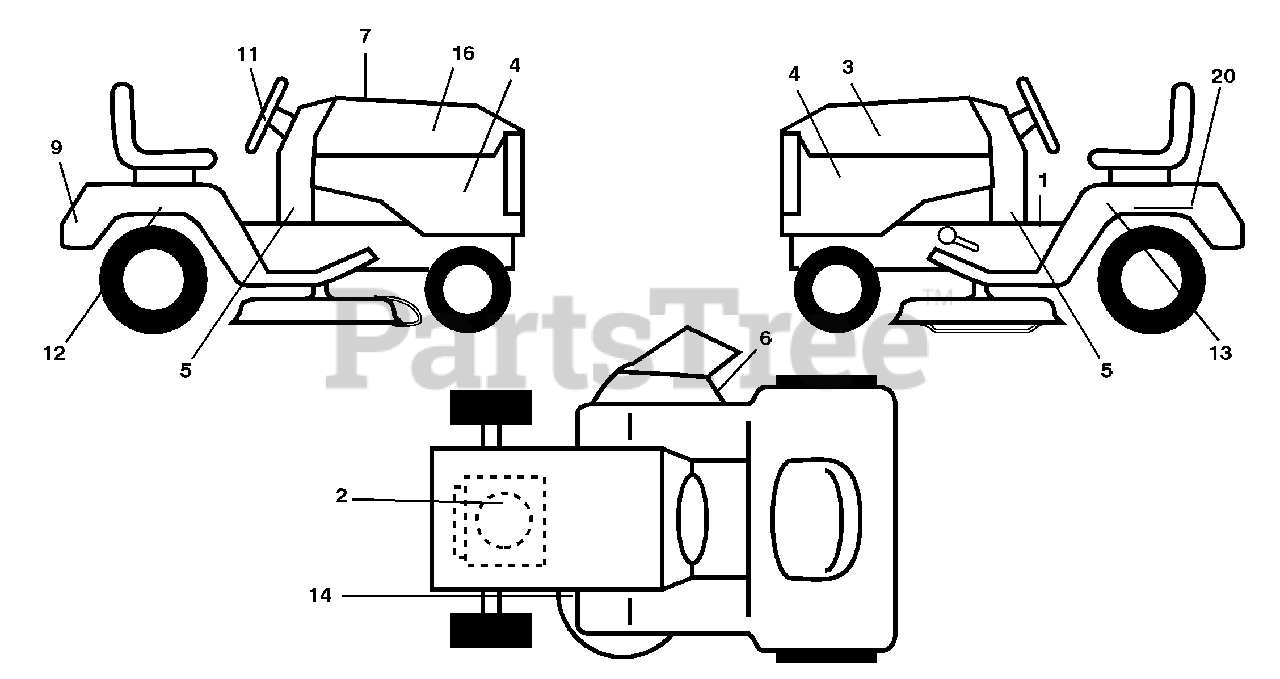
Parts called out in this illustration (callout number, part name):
1	Decal Oper
2	Decal Eng. H.P.
3	Decal Hood LH
4	Decal Side Panel Logo
5	Decal Lwr Dash
6	Decal Warning, Keep Hand Away
7	Decal Replacement Parts
9	Decal Fender Logo
11	Decal Ins Strg Whl
12	Decal Fend SD Rh
13	Decal Fend SD Lh
14	Decal V-Belt Schematic
16	Decal Hood Rh
20	Decal Bat Dan/Psn
20	Pad Footrest LH
20	Pad Footrest RH
20	Manual Operator's
